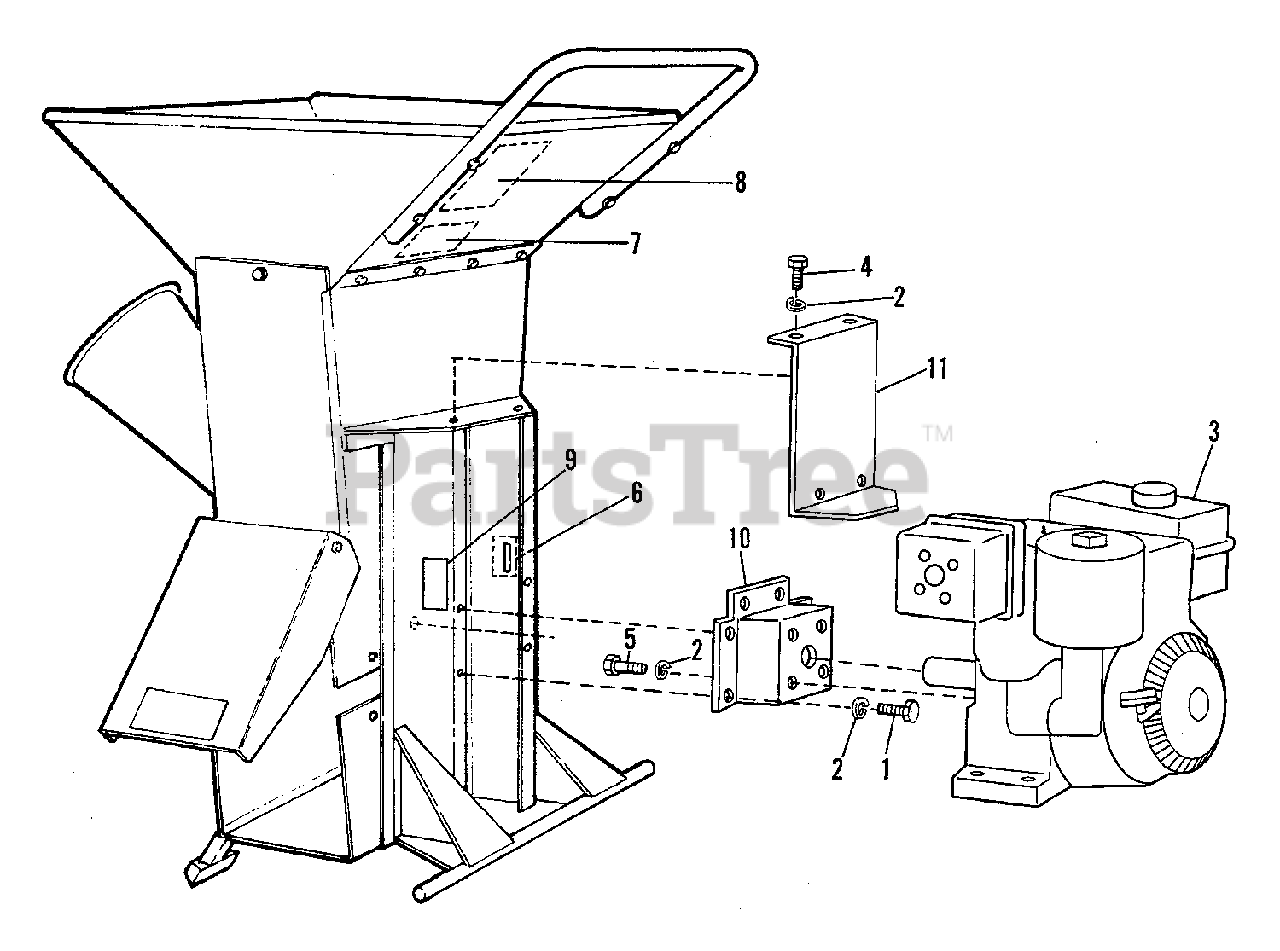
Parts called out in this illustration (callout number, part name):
1	CAPSCREW, Hex, 5/16-18 x 3/4
2	LOCKWASHER, 5/16, Split
3	ENGINE
4	CAPSCREW, Hex, 5/16-18 x 1/2
5	CAPSCREW, Hex, 5/16-24 x 3/4
7	DECAL, Danger
8	DECAL, Caution
9	DECAL, Patent, Chippers
10	SUPPORT AND COVER PLATE ASSEMBLY
